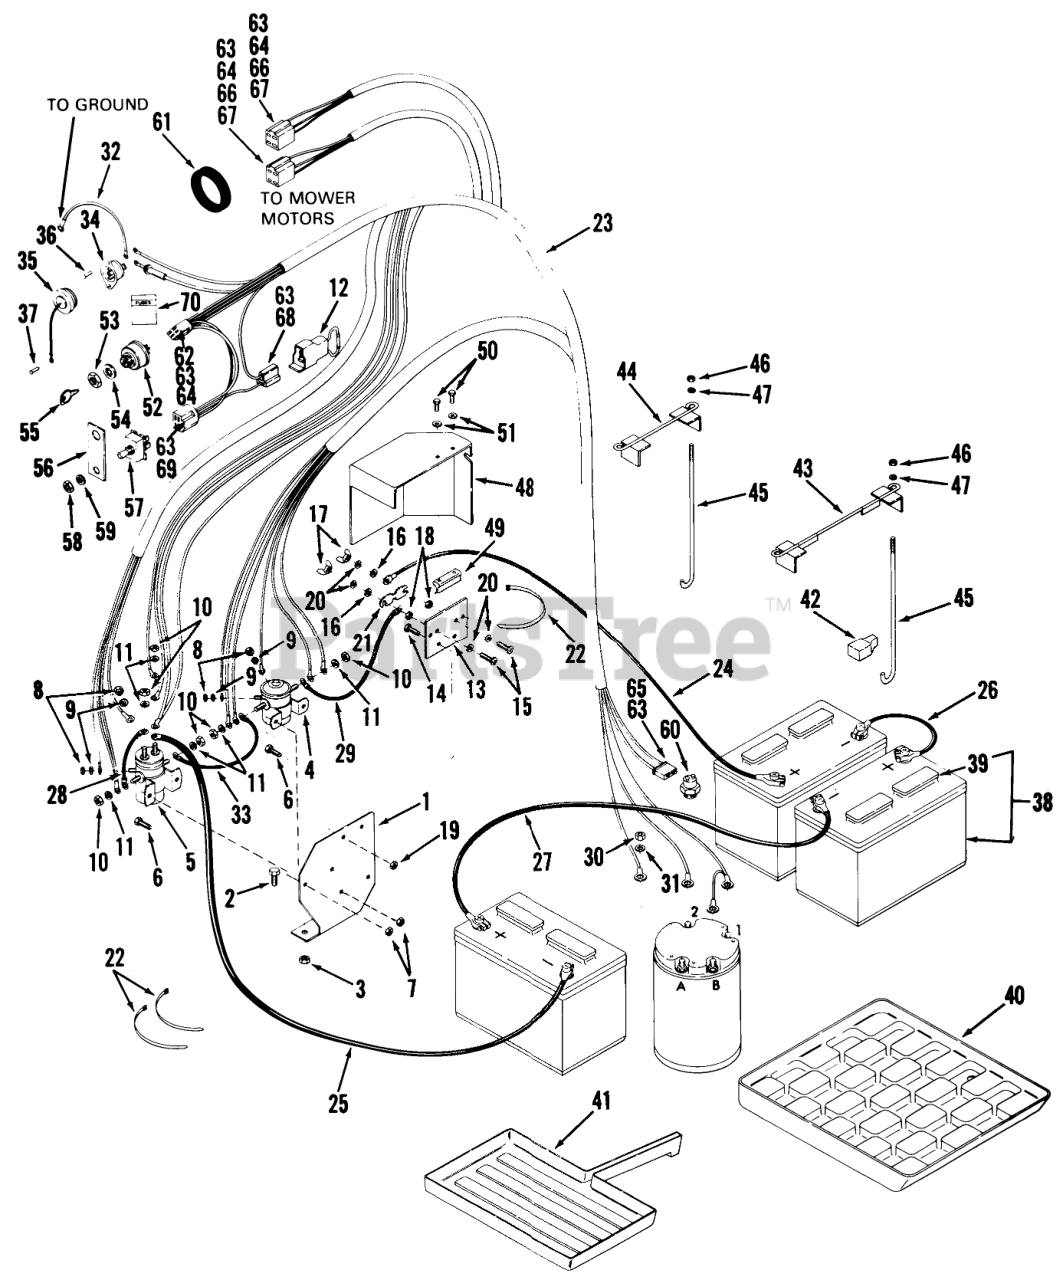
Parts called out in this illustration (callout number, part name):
36	RIVET
37	RIVET
38	Battery
39	Battery Cap
40	Battery Tray-Rear
41	TRAY BATTERY FRONT OBS
42	Terminal Cover
43	Hold Down Assembly
44	Assy-Hold Down
45	HOOK
46	Nut
48	Cover-Component Mounting Plate
49	Speed Nut/Clip Bracket
50	Screw 6-32 X 1/2
51	WASHER
52	SWITCH-IGNITION
53	Nut
54	Lockwasher 9/16 I.D.
55	Key-EL
56	Back-Up Plate-Ignition Switch
57	PTO Switch
58	Nut, 1/2-27
59	Lockwasher 1/2 Int. Tooth
60	SWITCH-INTERLOK CLUT
61	GROMMET
62	CONNECTOR-5 WAY-SERV
63	Terminal
64	TERMINAL-TAB RCPT
65	Connector Housing M
66	4-CONTACT CONNECTOR
67	Fem. Term.-Part of 23-12 Ga
68	Conn. Body-Part of 23
69	3-CONTACT CONNECTOR
70	FUSE
